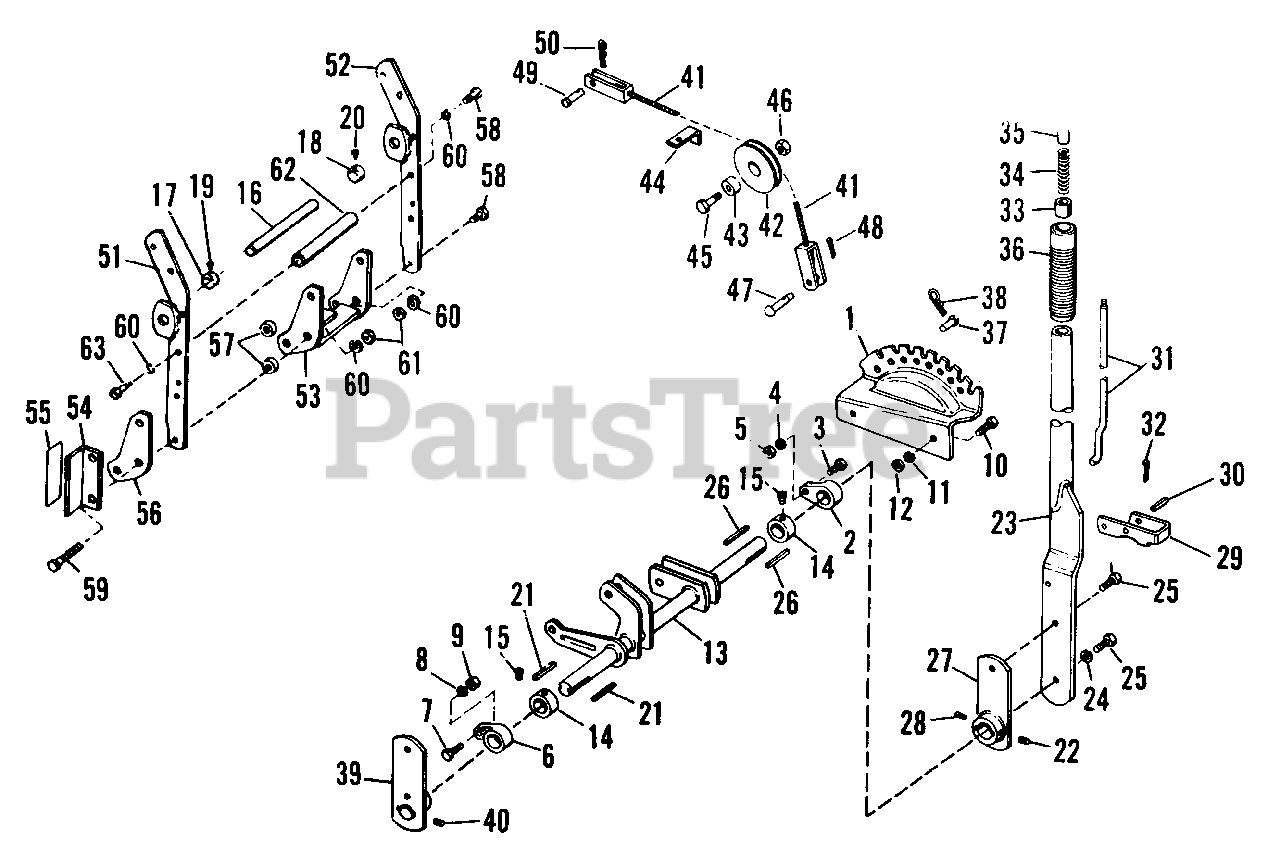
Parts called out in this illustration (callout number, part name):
1	Lift Lever Quadrant
2	Lift Lever Bearing
3	Hex Cap Screw, 5/16"-18 x 1-1/4"
4	Lock Washer, 5/16"
5	Full Hex Nut, 5/16"
6	Lift Lever Bearing
7	Hex Cap Screw, 5/16"-18 x 1-1/4"
8	Lock Washer, 5/16"
9	Hex Nut, 5/16"-18
10	Hex Cap Screw, 3/8"-16 x 3/4"
11	Lock Washer, 3/8"
12	Full Hex Nut, 3/8"
13	Lift Shaft Assy.
14	Set Collar
15	Set Screw Sq. Hd., 5/16"-18 x 3/8"
17	Set Collar
19	Set Screw, 5/16"-18 x 3/8"
20	Set Screw
22	Set Screw, 5/16"-18 x 1/4"
23	Lift Lever Assy.
24	Lock Washer, 3/8"
25	Hex Cap Screw, 3/8"-16 x 1"
27	Lift Lever Assy. Inner Section
28	Set Screw, 5/16"-18 x 1/4"
29	Lift Lever Latch
30	Roll Pin, 3/8" x 1-1/4"
31	Latch Rod
32	Cotter Pin, 3/32" x 3/4"
35	Thumb Button
36	Handle Grip
38	Spring Clip
39	Front Lift Lever Assy.
40	Set Screw, 5/16"-18 x 1/4"
41	Cable Assy., Lift
44	Cable Guard
46	Hex Jam Lock Nut, 3/8"-16
47	Pin
48	Cotter Pin, 3/32" x 7/8"
50	Spring Clip
53	Draw Bar Assy.
54	Plate, Decal
55	Film, Safety
58	Hex Cap Screw, 7/16"-14 x 1-1/4"
59	Hex Cap Screw, 7/16"-14 x 2-1/2"
60	Lock Washer, 7/16"
61	Full Hex Nut, 7/16"
63	Hex Cap Screw, 7/16"-14 x 1-3/4"
